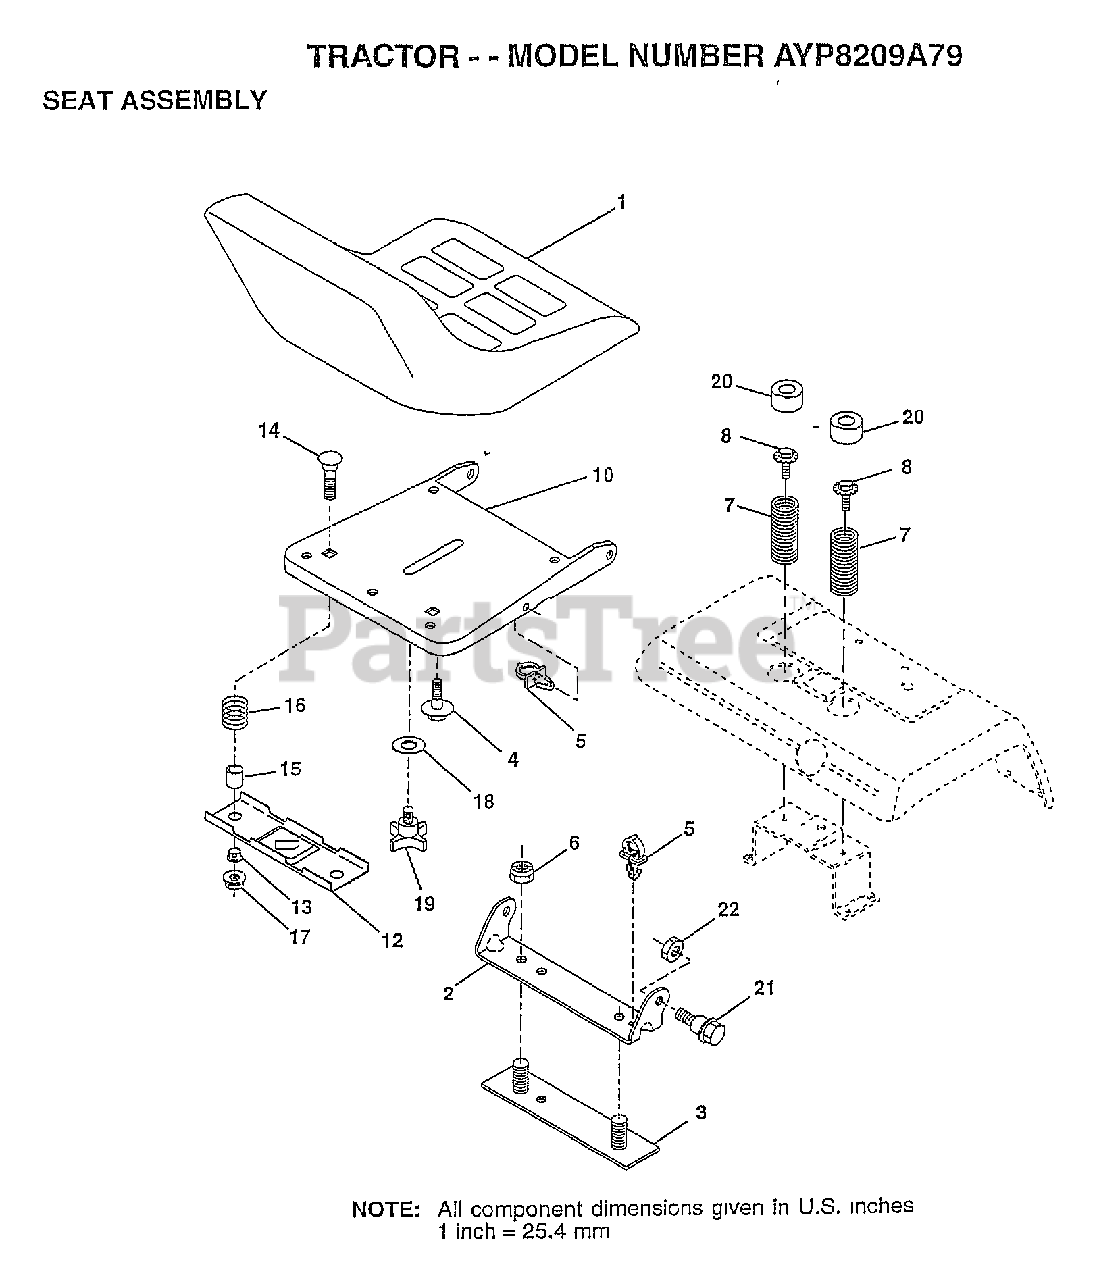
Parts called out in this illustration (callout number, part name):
2	BRACKET PVT SEAT
3	STRAP ASM FENDER
4	"BOLT,SHOULDER"
5	CLIP.PUSH-IN.HING
6	NUT
7	SPRING COMPRESSIO
8	BOLT.5/16-18.UNC
10	PAN-SEAT
12	BRKT SWITCH
13	BUSHING
15	SPACER SPLIT
16	SPRING COMPRESSED
18	WASHER
19	"KNOB 1/2"" YT"
20	CAP SPRING
21	"BOLT,SHOULDER"
